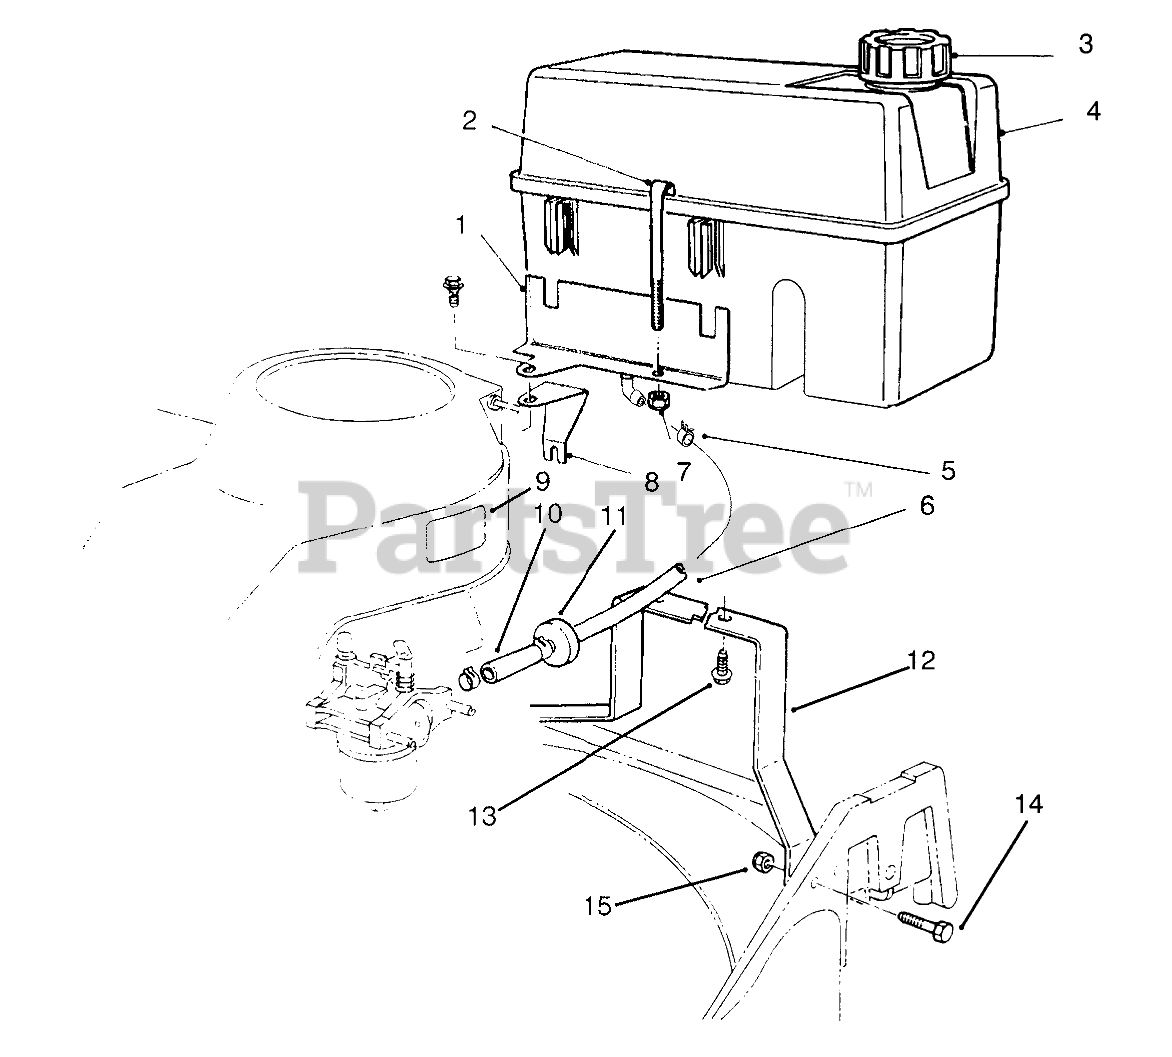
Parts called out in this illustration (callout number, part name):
1	Bracket Tank
2	RETAINER - FUEL TANK
3	CAP-VENTED GAS 50 TO 1
4	Tank-Gas
5	CLAMP-FUEL LINE
6	HOSE-FUEL
7	NUT-LOCK, NI
8	Support-Bracket
9	DECAL - FUEL
10	LINE-GAS
11	FILTER-FUEL
12	Base-Tank, Fuel
13	SCREW-HWH
14	SCREW-HH
15	NUT-LOCK, NI
